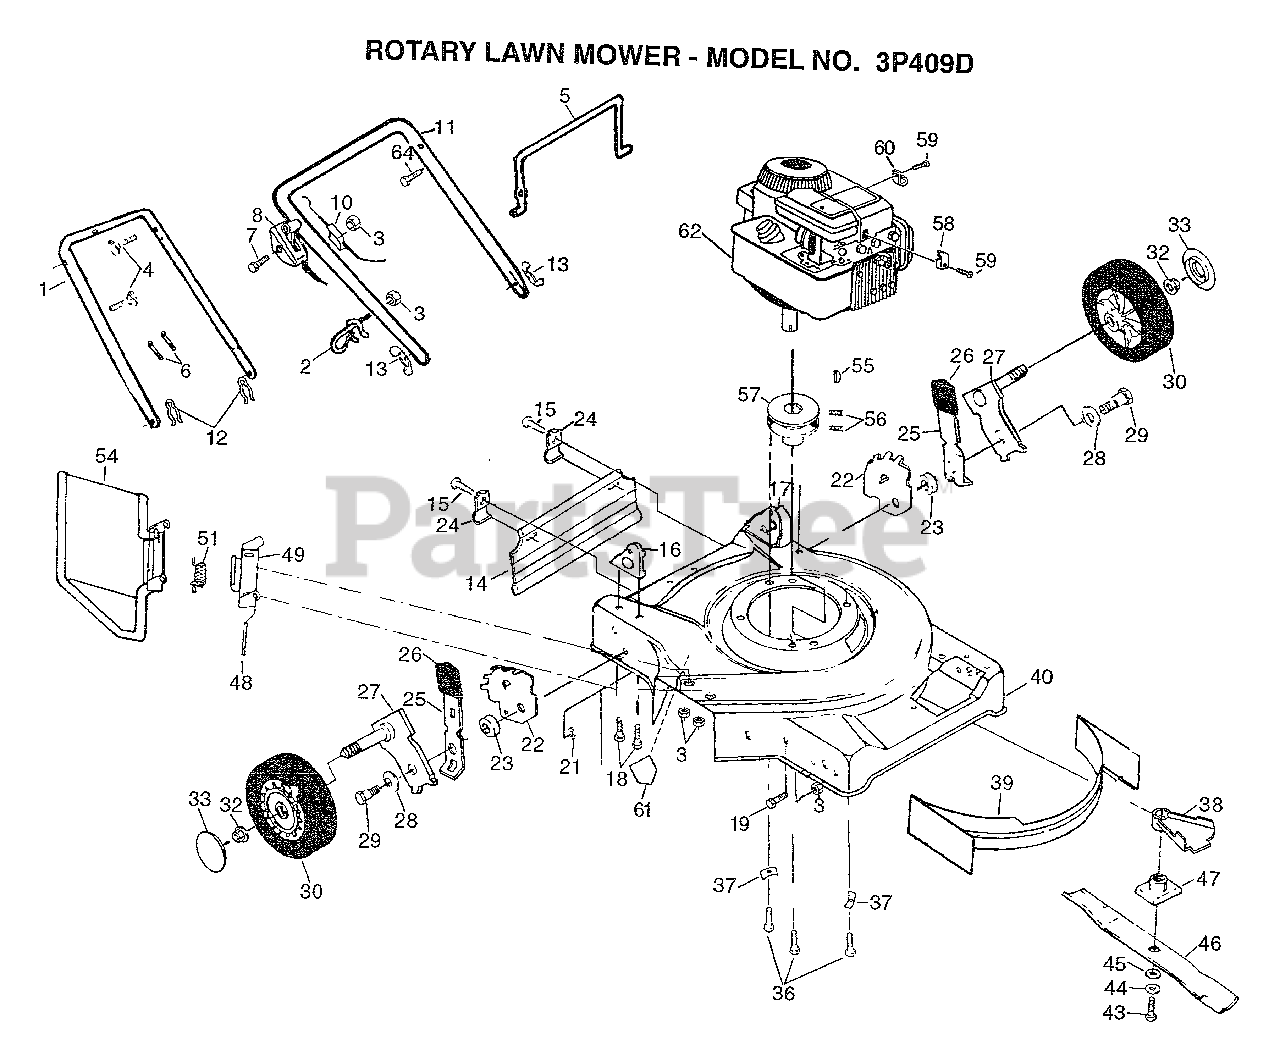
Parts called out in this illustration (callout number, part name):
1	HANDLE LOWER
2	ROPE GUIDE
4	BOLT.HANDLE.LM
5	BAIL.CNTRL.STD.BL
7	PAN HEAD SCREW
8	CONTROL THROTTLE
10	"CABLE,ENG ZONE CO"
12	HAIRPIN COTTER
13	"NUT,WING PM"
14	SKIRT.REAR.FGD.22
15	TAPPING SCREW
16	HDLE BRKT ASSY.RH
17	HDLE BRKT ASSY LH
18	SCREW 5/16-18X3/4
19	SCREW
21	LOCKNUT PM
22	BRACKET.ADJ.9POS.
23	SPACER.HEIGHT.ADJ
24	"BRKT,DEFL PM"
25	SPRING SELECTOR
26	KNOB PM
27	ARM.AXLE.ASM.BZP.
28	"WASHER, BELLEVIL."
29	BOLT SHLD 3/8-16
30	WHEEL.8X2.PR.RAD.
32	HEX FLANGE LOCKNT
33	HUB CAP
36	BOLT.ENG.3/8-16
39	BAFFLE FRONT 22SD
40	KIT.HSG.22SD.FWGD
43	SCREW
44	LOCKWASHER
45	"WASHER,HARDEN"
46	"BLADE.MULCH.22"""
47	ADAPTOR.BLADE.LM
48	ROD.HINGE.COMBI-C
49	BRACKET.HINGE.W/F
51	SPRING.HINGE
54	GUARD.DISCH.22SD.
55	HI PRO KEY PM
56	SCREW
57	ENGINE.PULLEY.FWG
58	CABLE CLAMP
59	SCREW PM
60	GUIDE CLIP PM
61	DECAL HYT
